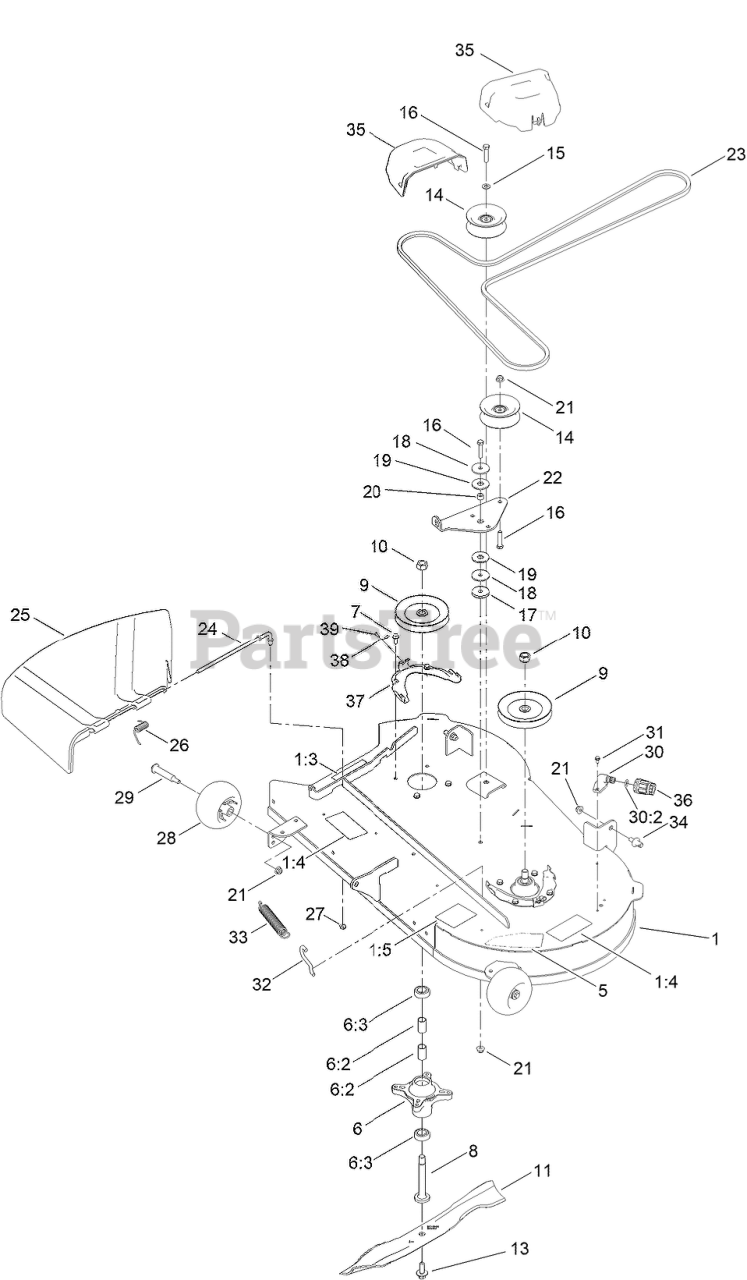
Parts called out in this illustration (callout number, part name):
1	42IN DECK AND DECAL ASM
1:3	DECAL-DANGER
1:4	DECAL-DANGER, DECK
1:5	DECAL-ROUTING, BELT
5	DECAL-DECK
6	SPINDLE ASM
6:2	SPACER
6:3	BEARING-BALL
7	SCREW-TAPTITE
8	SHAFT-SPINDLE
9	Pulley
10	NUT-HEX
11	BLADE-21.6 IN
13	BOLT-BLADE, SEMS
14	PULLEY-IDLER, FLAT
15	WASHER-FLAT
16	SCREW-HH
17	WASHER-PLAIN
18	WASHER-REBOUND
19	WASHER-FRICTION, COMPOSITE
20	SPACER
21	NUT-HF, NI
22	ARM-IDLER
23	V-BELT
24	ROD-PIVOT
25	DEFLECTOR-DISCHARGE
26	SPRING-TORSION
28	ROLLER-SCALP, ANTI
29	BOLT-SHOULDER
30	FITTING-WASHOUT
30:2	O-RING
31	SCREW-HWH
32	HOOK-RETURN SPRING
33	SPRING-EXTENSION
34	PIN-DECK
35	COVER-BELT
36	CONNECTOR-HOSE
37	BRACKET-COVER, BELT
38	PIN-HAIR
39	SCREW
